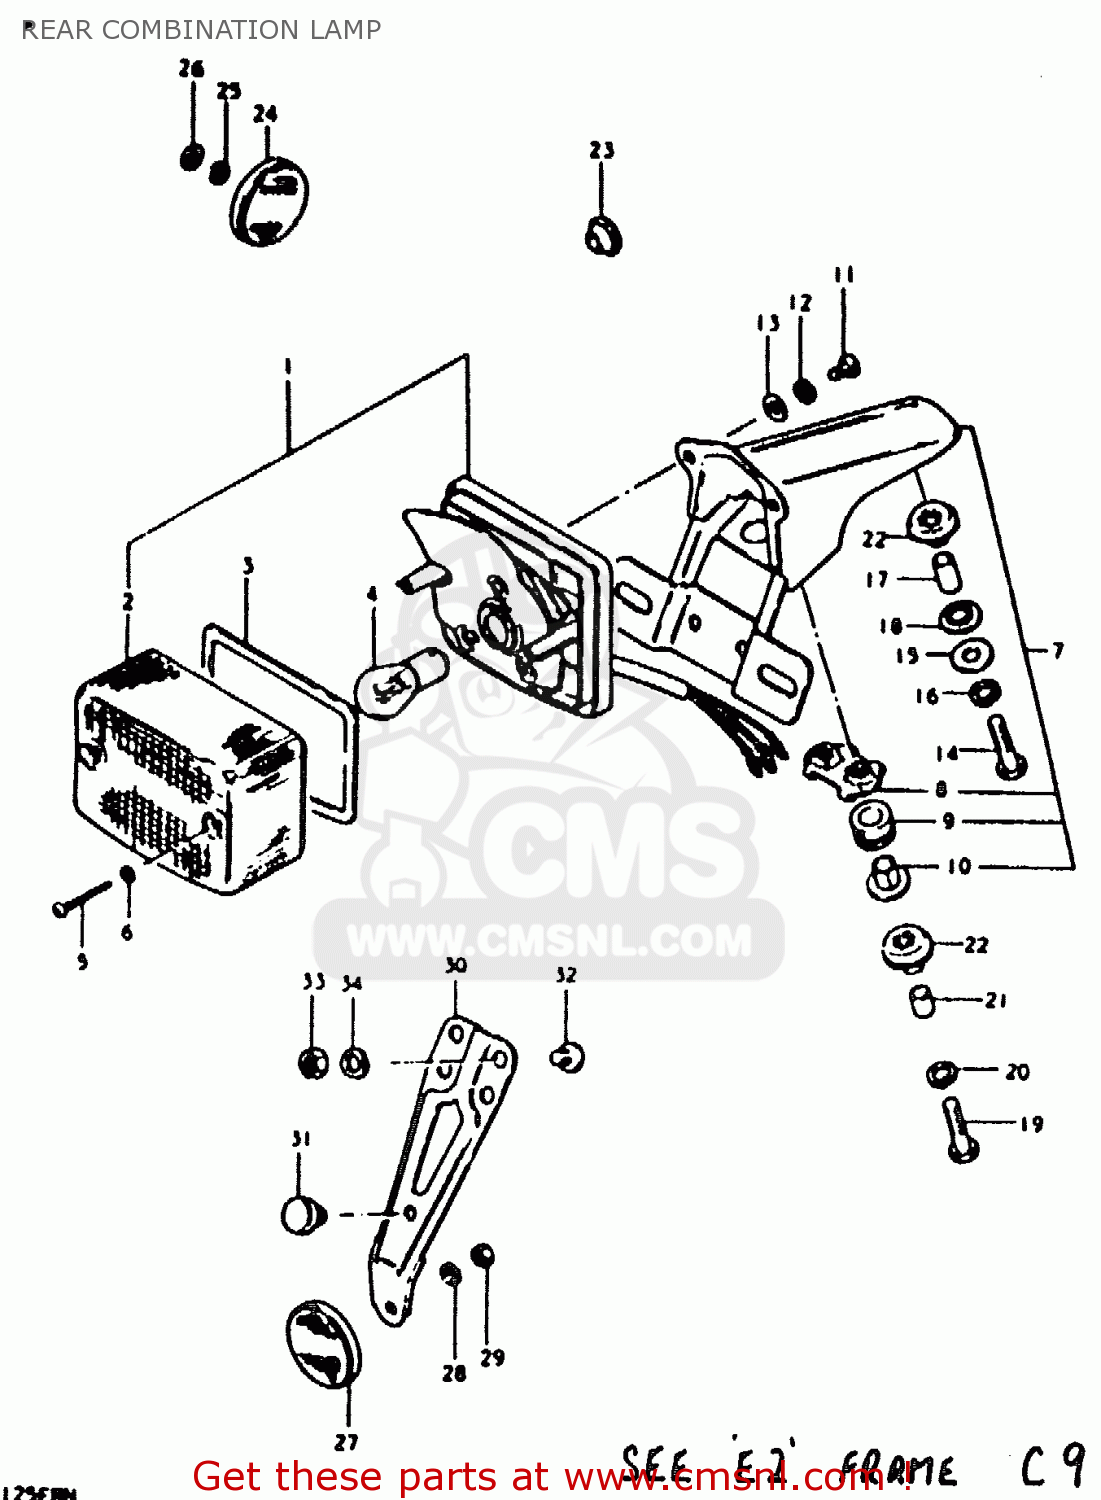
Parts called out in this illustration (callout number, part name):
1	LAMP UNIT, REAR COMBINATION
2	LENS
3	GASKET (NAS)
4	BULB(6V10/3W,STANLEY,A4854H)
5	BOLT
6	GASKET (NAS)
7	BRACKET ASSY
8	PLATE
9	CUSHION
10	SPACER
11	SCREW
12	WASHER,LOCK
13	WASHER
14	BOLT
15	WASHER (6.5X20X1.2)
16	LOCK WASHER
17	SPACER
18	CUSHION
19	BOLT 6X40
20	LOCK WASHER
21	SPACER (6.8X10X11.5)
22	CUSHION
23	GROMMET
24	REFLEX REFLECTOR,FR
25	LOCK WASHER
26	WASHER
27	REFLEX REFLECTOR,RR
28	LOCK WASHER
29	NUT
30	BRACKET
31	CUSHION
32	SCREW, PLATE
33	NUT 6MM
34	LOCK WASHER
